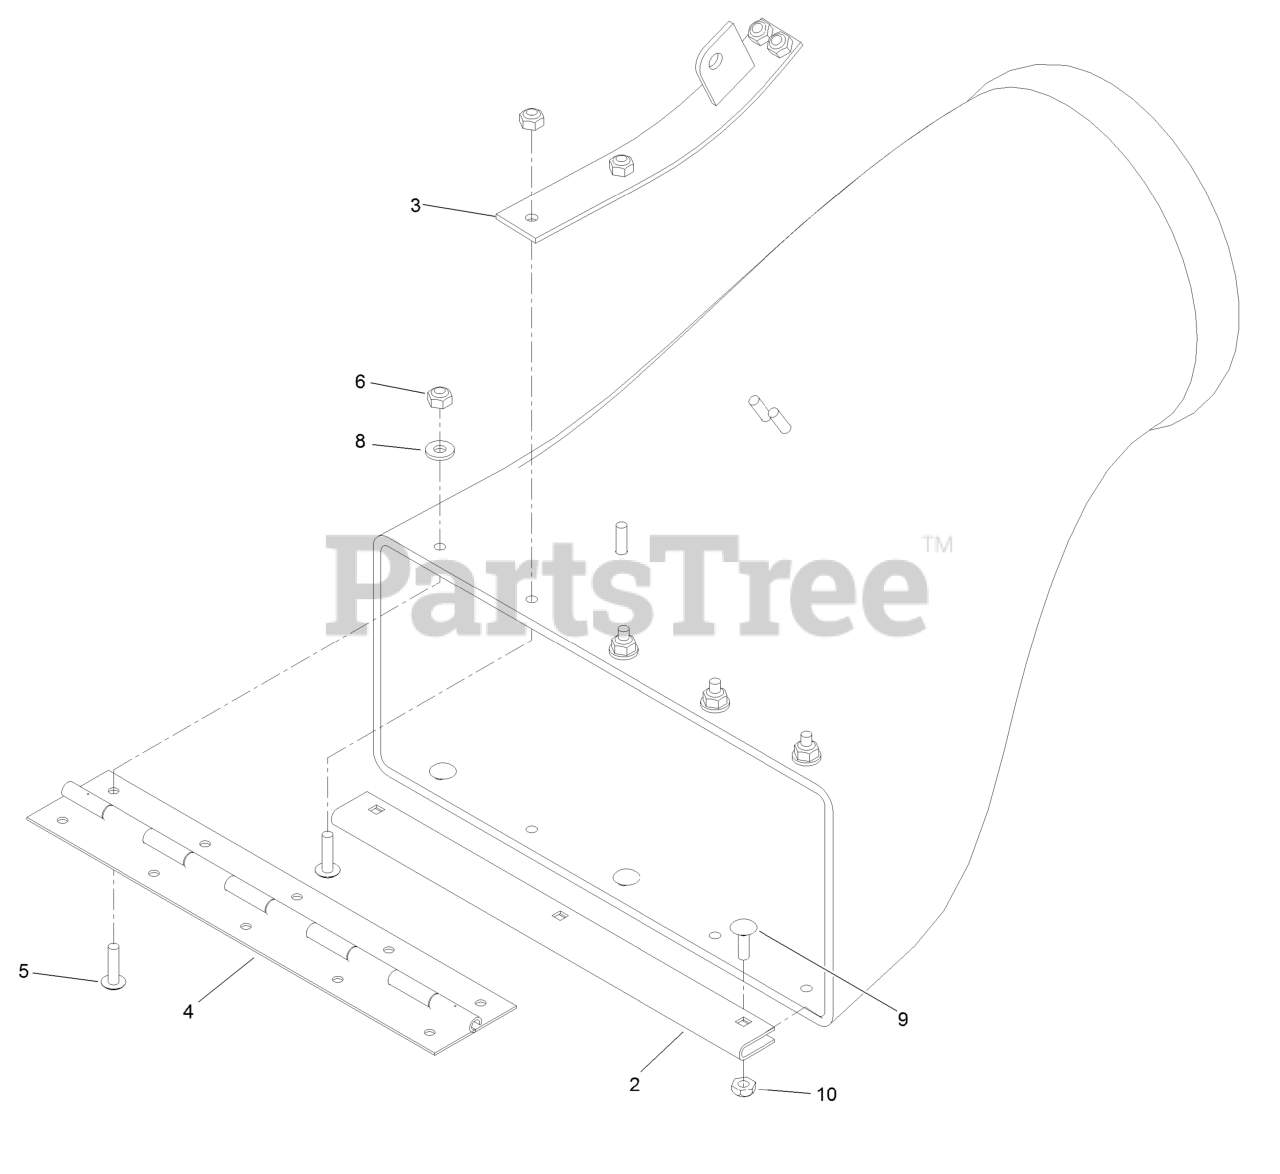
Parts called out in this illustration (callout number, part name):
2	Guard-Plenum
3	Mount-Spring
4	Hinge-Piano
5	Screw-Head, Truss
6	Nut-Lock, NI
8	Washer-Flat
9	Bolt-CARR
10	Nut-Lock, NI
